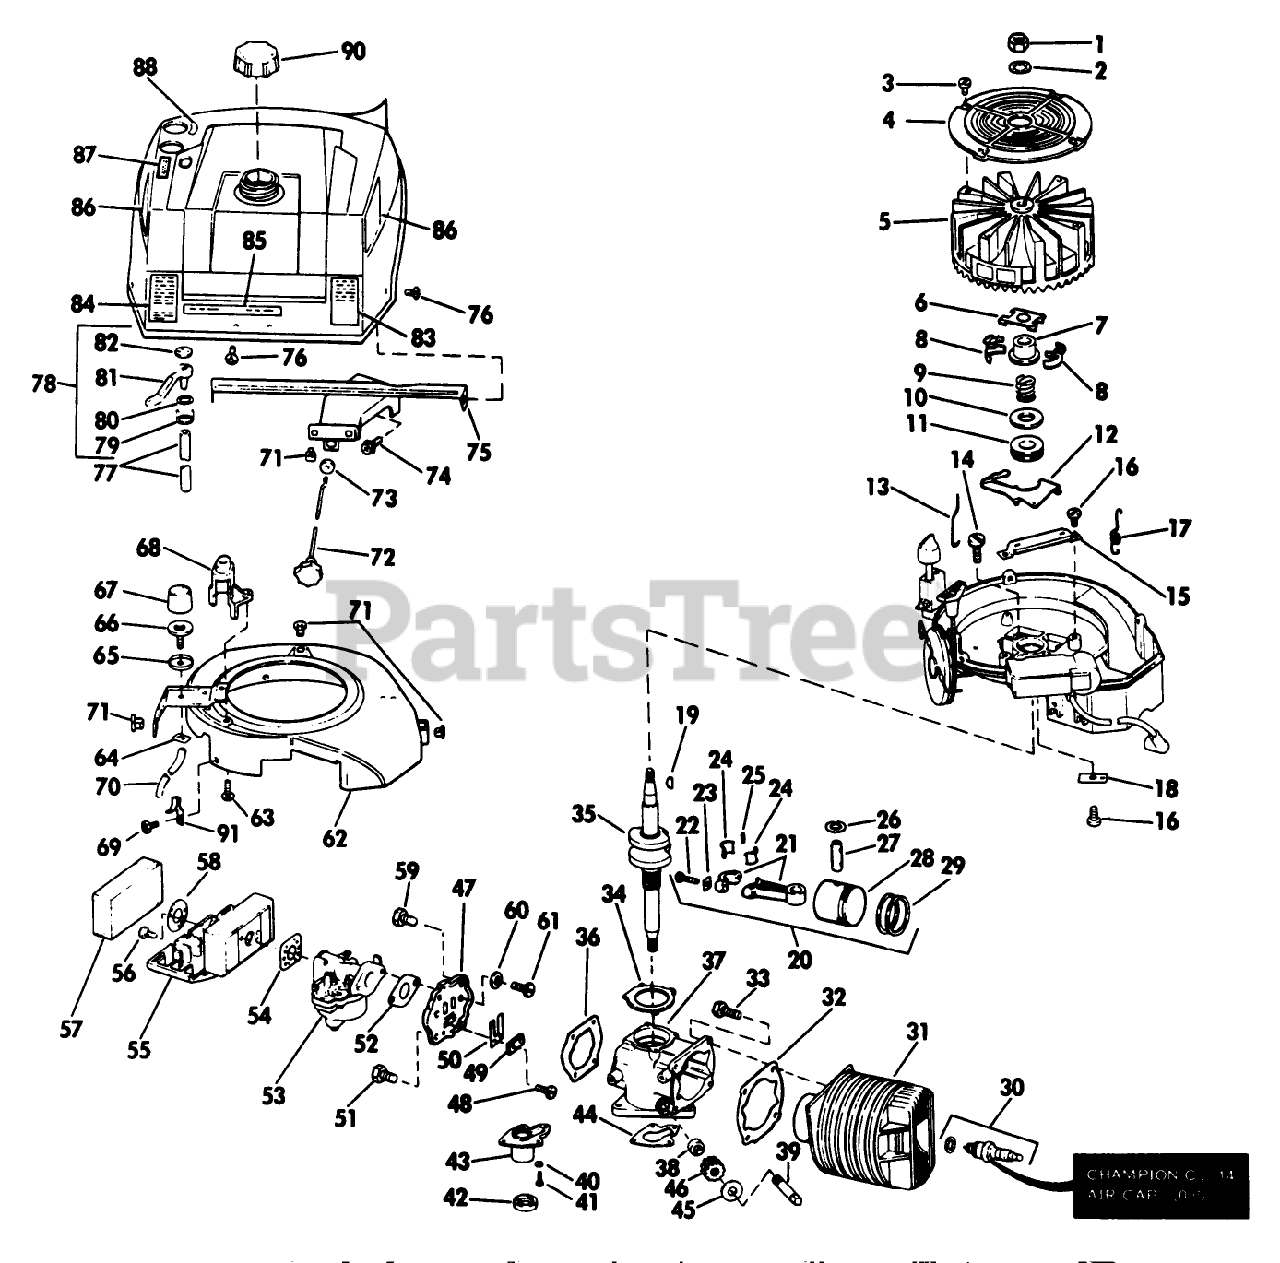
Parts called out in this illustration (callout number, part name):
3	SCREW F
7	COLLAR S
9	SPRING S
12	LEVER-GOVERNOR S
15	BRACKET
16	SCREW S
24	LINER ASM
26	RING-RETAINING
30	Spark Plug
32	GASKET S
34	GASKET S
36	GASKET S
43	GEAR COVER S
44	GASKET-CVR S
45	THRUST WASHER
46	GEAR, DR SHAFT S
47	REED PLATE AY. S
49	PLATE-BACKUP, REED
51	SCREW S
52	GASKET S
54	GASKET S
56	SCREW S
57	AIR FILTER S
58	WASHER S
59	SCREW S
64	LOCKNUT S
65	CUP-BULB
71	NUT-CLIP
74	SCREW S
75	BRACKET
76	SCREW S
80	WASHER S
